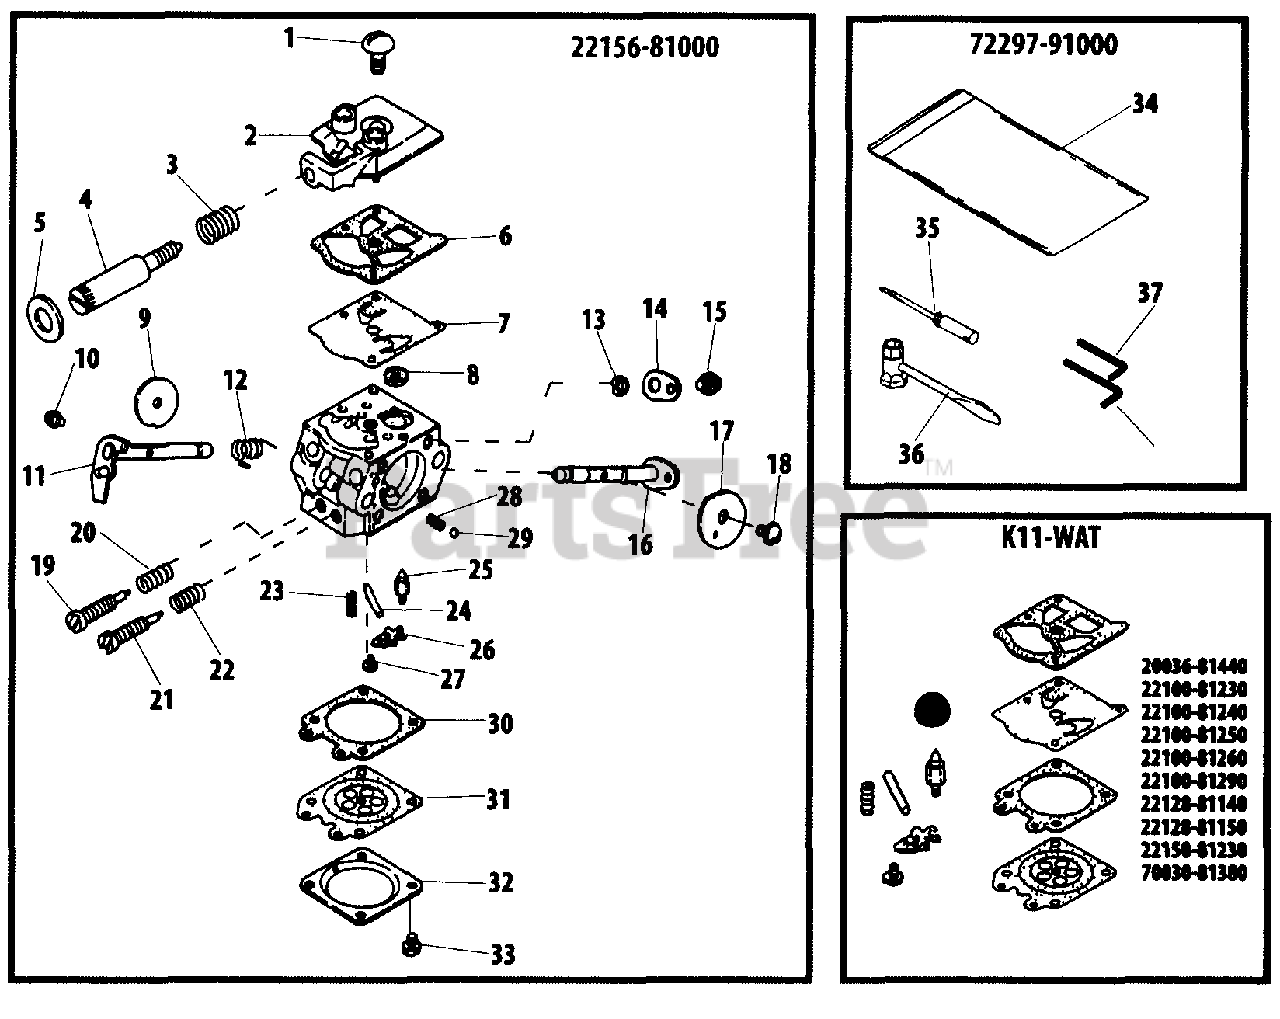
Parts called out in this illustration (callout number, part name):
1	SCREW
2	COVER ASSY, PUMP
3	SPRING, IDLE ADJUST
4	SCREW, IDLE ADJUST
5	SEAL, COLLAR
6	GASKET, PUMP
7	DIAPHRAGM, PUMP
8	SCREEN, FUEL INLET
9	VALVE, THROTTLE
10	SCREW ASSY
11	SHAFT, THROTTLE
12	SPRING, THROTTLE RETURN
13	E-RING
14	LEVER, THROTTLE
15	SCREW
16	SHAFT, CHOKE
17	VALVE, CHOKE
18	SCREW
19	NEEDLE, LOW SPEED
20	SPRING, NEEDLE
21	NEEDLE, HIGH SPEED
22	SPRING, HIGH NEEDLE
23	SPRING, METERING LEVER
24	PIN, METERING LEVER
25	VALVE, INLET NEEDLE
26	LEVER, METERING
27	SCREW, METERING LEVER PIN
28	SPRING
29	BALL, CHOKE FRICTION
30	GASKET, METERING DIAPHRAGM
31	DIAPHRAGM, METERING
32	COVER, METERING DIAPHRAGM
33	SCREW
34	BAG, TOOL
35	SCREWDRIVER
36	T-WRENCH 13×19 MM
37	WRENCH, ALLEN 3 MM
38	WRENCH, ALLEN 4 MM
22156-81000	CARBURETOR
72297-91000	TOOL KIT, SERVICE
K11-WAT	REPAIR KIT
